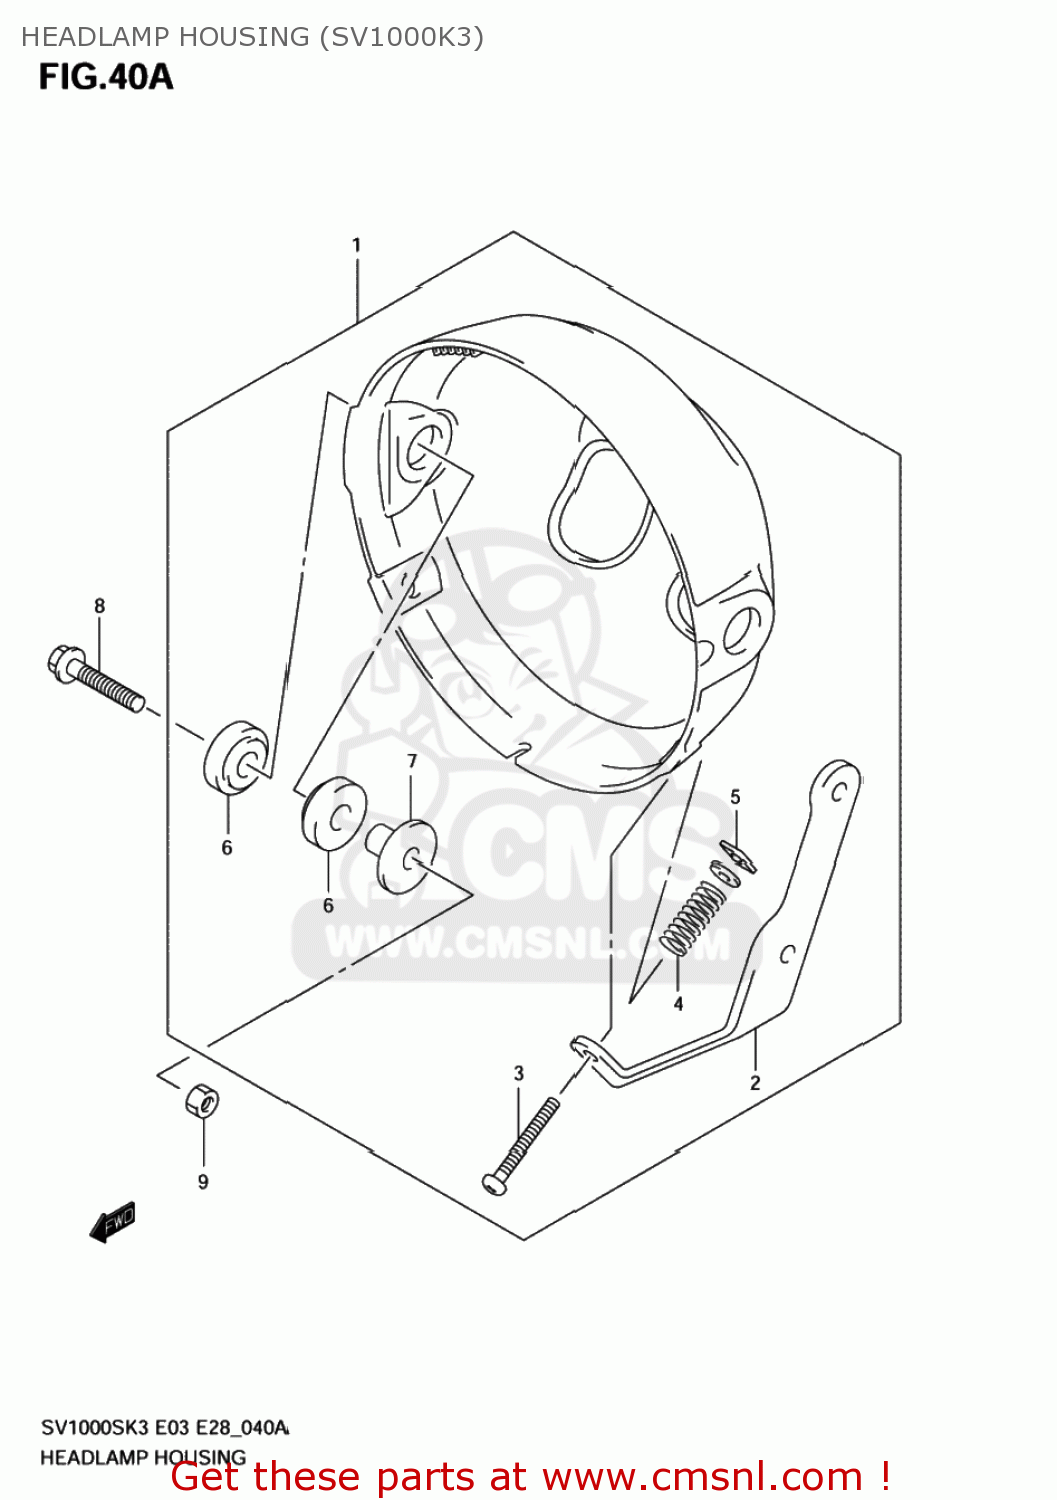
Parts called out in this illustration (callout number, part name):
1	HOUSING ASSY,HEADLAMP
2	PLATE,HEADLAMP HOUSING
3	SCREW(5X45)
4	SPRING,HEADLAMP ADJUSTER
5	NUT,HEADLAMP ADJUSTER
6	CUSHION
7	SPACER(8.6X12X21.3)
8	BOLT(8X35)
9	NUT
